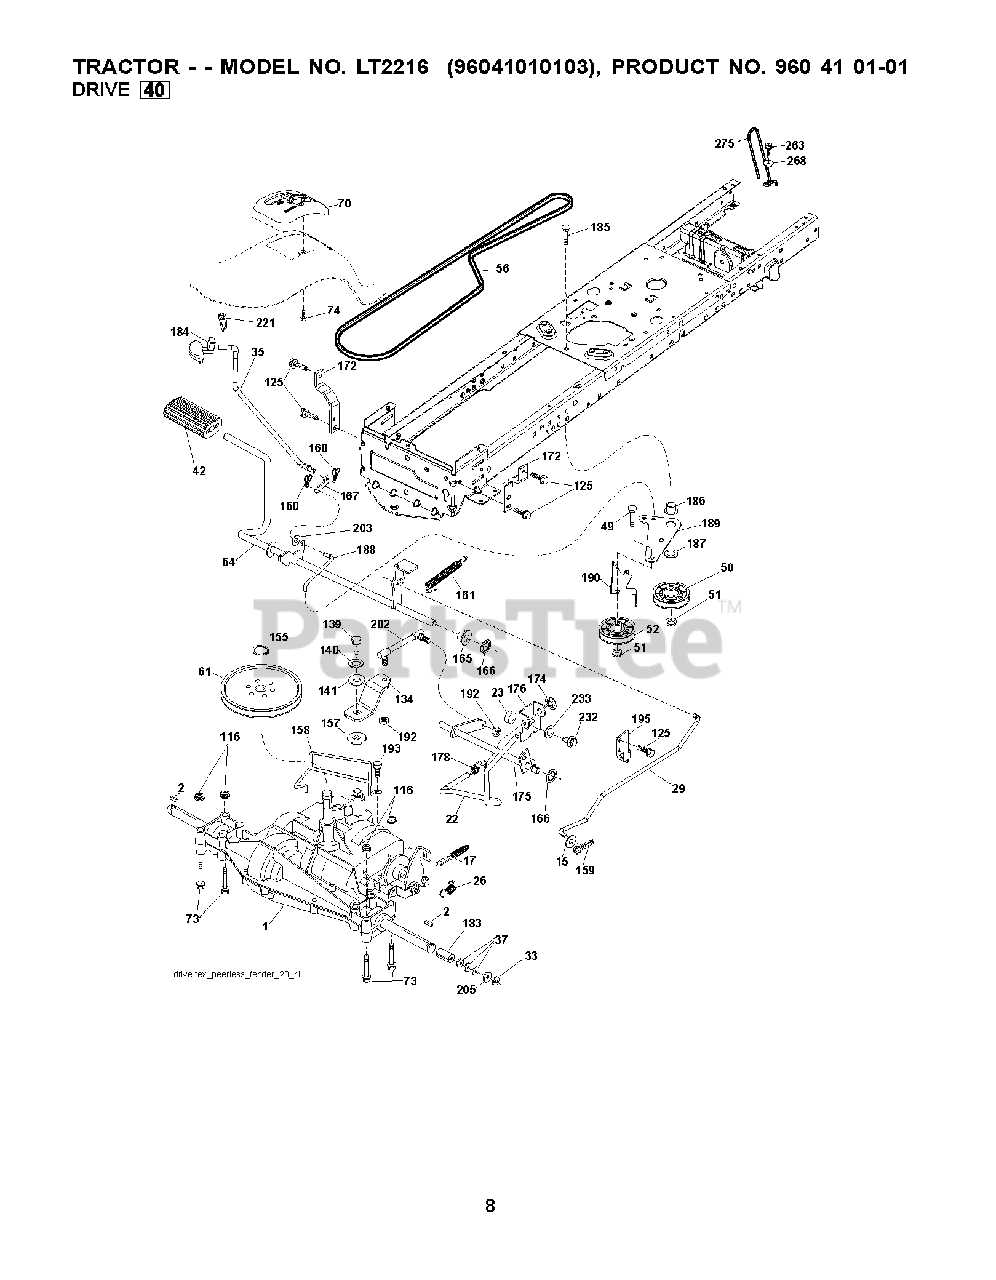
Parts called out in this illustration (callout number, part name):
2	SQUARE KEY
17	SPRING.BRAKE.PEERLESS.TEX
22	ROD.SHIFT.FENDER.TLT.2006
23	KNOB.DUCKHEAD.1/2
26	SPRING.BRAKE.RTN.GR.DR
29	ROD.BRAKE.PEERLESS
33	E-RING LT
35	ROD, BRAKE, PARK
42	PEDAL COVER T
49	BOLT
50	IDLER.FLAT.910.OFFSET
51	NUT LOCK FLG 3/8-16 UNC
52	IDLER.V-GROOVE.910.OFFSET
56	V-BELT.TRACTOR.DRIVE.P
61	PULLEY TRANS
64	SHAFT.ASM.PEDAL.BRAKE.
70	CONSOLE.SHIFT.
73	BOLT
74	SCREW.HI-LO.CONSOLE
116	NUT LOCK HEX FLANGE 5/16-18
125	SCREW
134	ARM SHIFT
139	BOLT 1/4-28X3/4
140	LOCKWASHER
141	WASHER LT
155	RETAINING RING LT
157	WASH-SHFT PLT LT
158	KEEPER.PMS.18/20.D4365
159	COTTER PIN
160	RETAINER CLIP
161	SPRING, RETURN LT
165	BUSHING.SHAFT.BRAKE.HAND
166	NUT.PUSH.625
167	LATCH.BRAKE.SPRING
172	STRAP.TRQ.LH.GEAR.DRIV
174	NUT.PUSH.500.2006
175	SHAFT ASM SHIFT
176	ARM.CLEVIS.ROD.SHIFT
178	SPRING.SHIFT.GT2006
183	SPACER AXLE
184	HANDLE.PARKING.BRK.PRED.LT.RED
186	SPACER.RETAINER
187	WASHER 12/32X2X10GA
188	LINK.CLUTCH.GROUND.DRIVE
189	BELLCRANK.GROUND.DRIVE.TEX.
190	KEEPER.BELLCRANK.DRIVE
192	NUT LOCK CENTER 1/4 -28 FNTHD
193	SCREW 5/16"
195	BRKT.ROD.BRAKE.PEERLES
202	LINK.SHIFT.PMST.18"
203	WASHER
221	RETAINER.SPRING.CLIP.H
232	BOLT FIN HEX 7/16-14 X 1
233	WASHER SERRATED
263	SCREW, 3/8-16X3/4
268	WASHER
